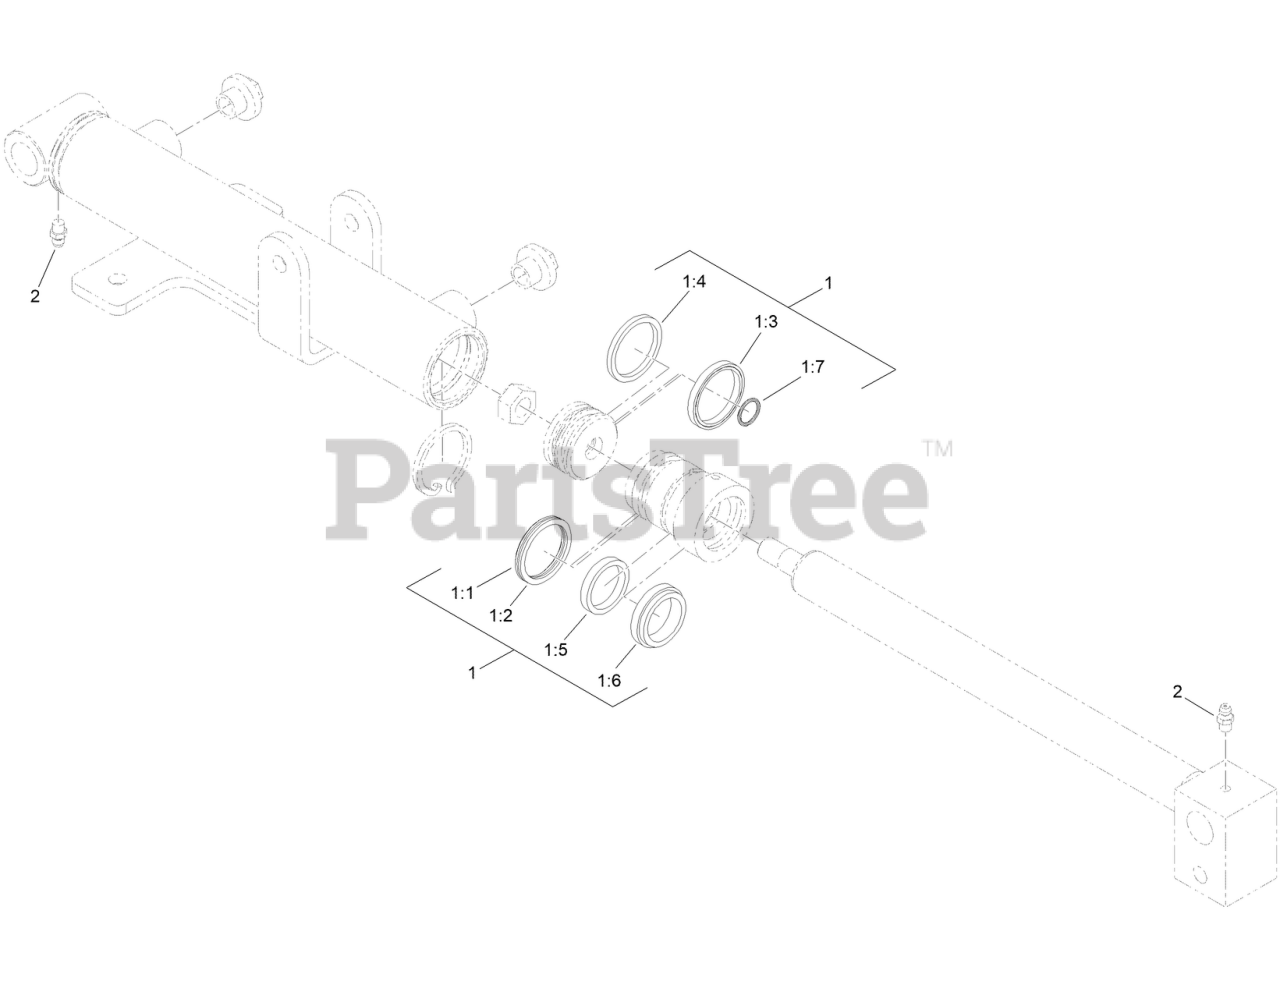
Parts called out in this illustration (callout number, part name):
1	CYLINDER REPAIR KIT
1:1	O-Ring
1:2	Backup
1:3	Psp Seal
1:4	Wear Ring-Ht
1:5	Bt Seal
1:6	Dust Seal
1:7	O-Ring
2	Zerk 1/4-28 Str Thrd Forming
